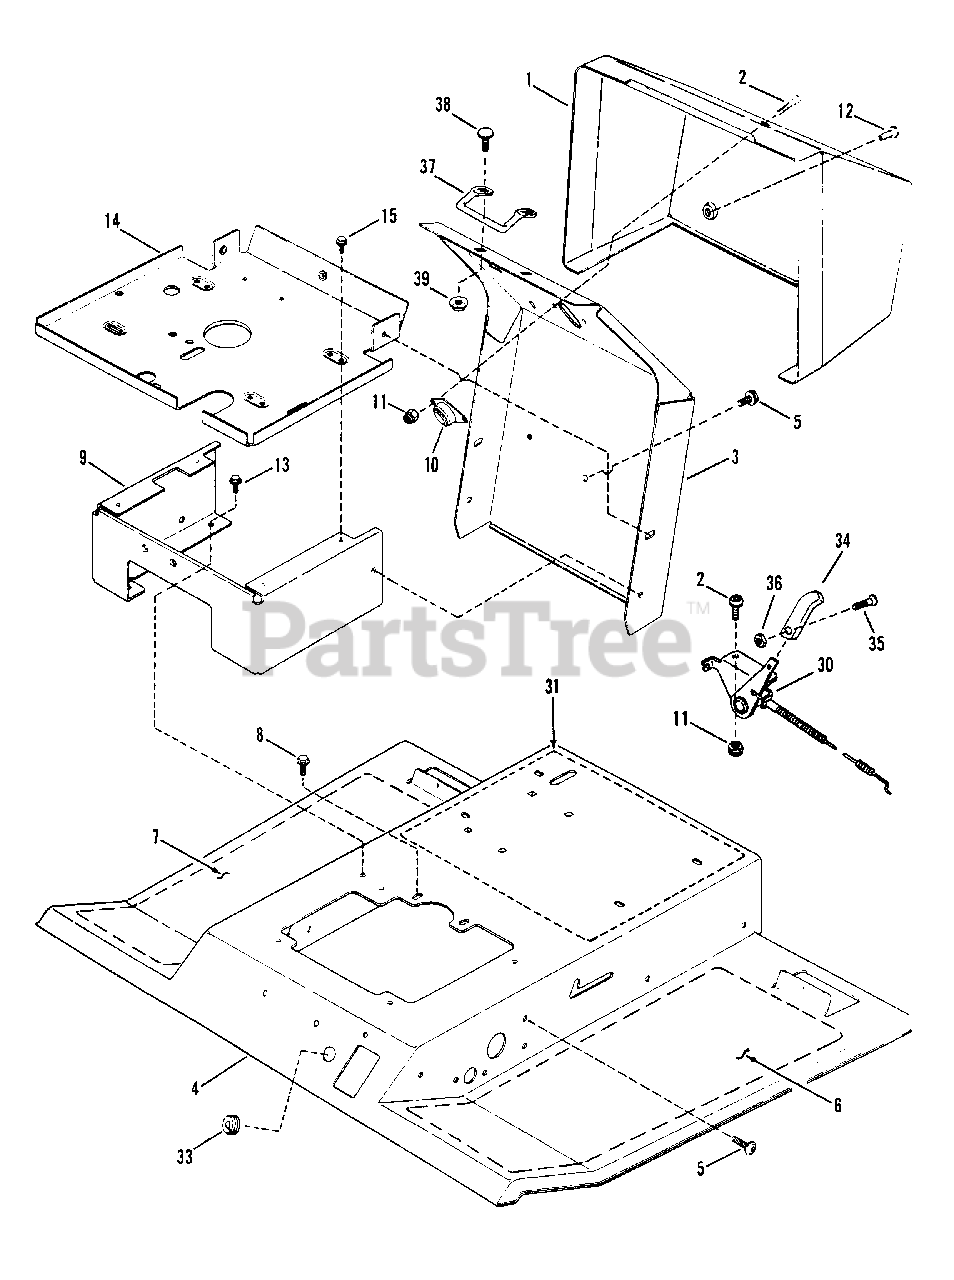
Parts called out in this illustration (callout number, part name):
1	PANEL, Dash
2	SCREW, 1/4-20x1" Phillips
3	SUPPORT, Steering Shaft
4	CHANNEL, Foot Rest
5	SCREW, 5/16-18x7/8" Torx, S.T.
6	TREAD, Left Side (Non-Skid)
7	TREAD, Right Side (Non-Skid)
8	SCREW, 5/16-18x5/8" H.C.S.T.
9	MOUNT, Fuel Tank/Battery
10	FLANGE ASSM'Y., Steering Shaft .75" ID Bearing
11	NUT, 1/4-20 Hex
12	SCREW, #10-24x1/2" Self-Tapping
13	SCREW, 5/16-18x1/2" Self-Tapping
14	PLATE, Fuel Tank & Battery Mount
15	SCREW, 1/4-20x1/2" H.C.S.T.
30	CONTROL, Throttle 41.6" Long
31	DECAL, Caution & Instruction
33	GROMMET, 5/16 I.D. for .75 Hole (No Longer available)
34	HANDLE, Throttle Control
35	SCREW, #8-32x3/8" Rec. Fill. Hd.
36	NUT, #8-32 Hex
37	ROD, Hood Latch (No longer available, try using 7033828)
38	BOLT, 1/4-20x5/8" Flat Hd. Carr.
39	NUT, 1/4-20 Hex Flg. Lock
